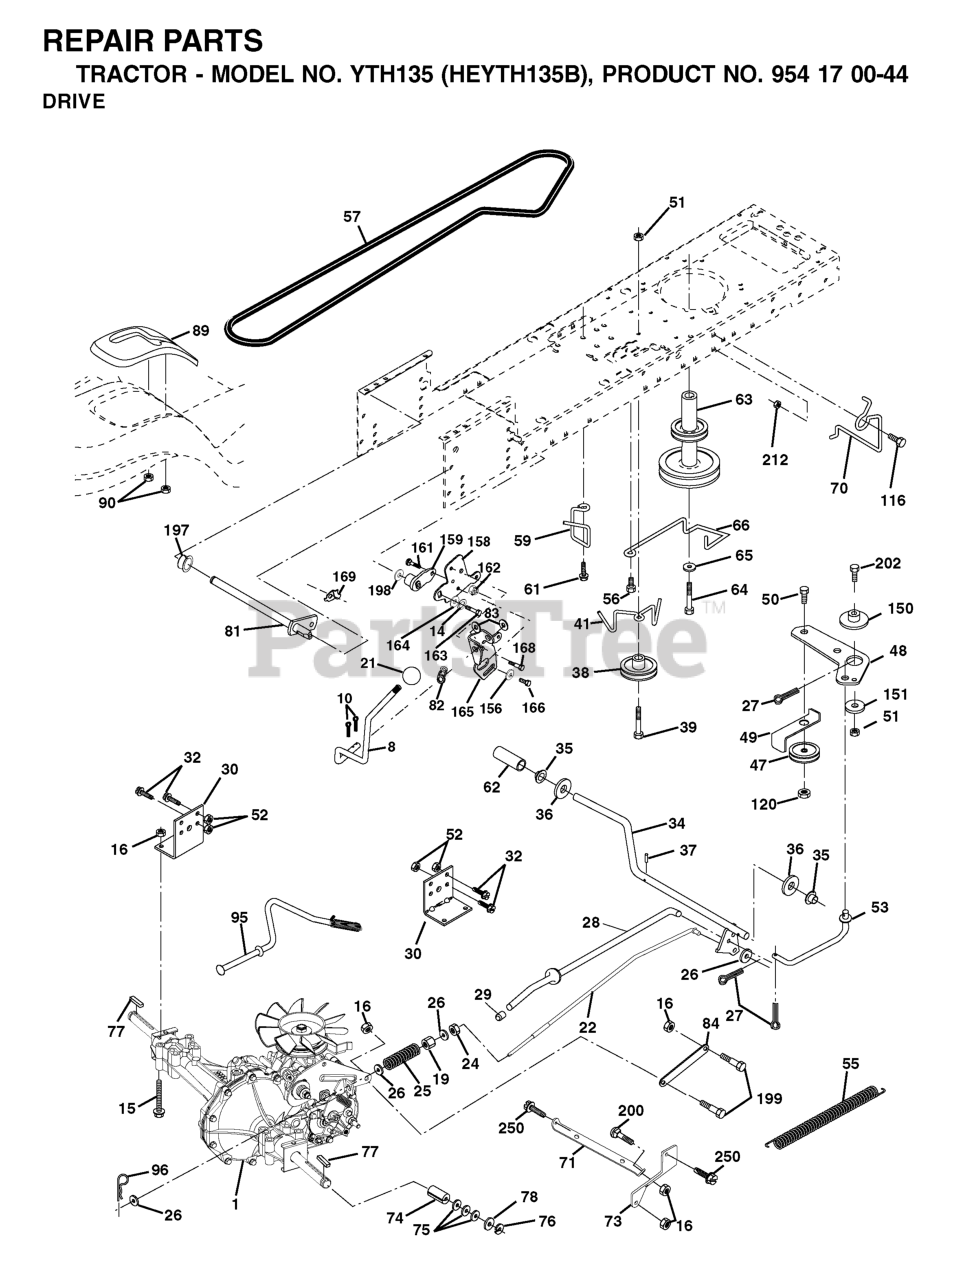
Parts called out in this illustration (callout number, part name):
8	ROD SHIFT FENDER ADJUST STLT
10	PIN COTTER
14	LOCKWASHER
15	BOLT HEX 5/16-18 GR 5
16	NUT.71038.31-18.HEX.NYLOCK
19	NUT
21	KNOB.DUCKHEAD.1/2
22	ROD BRAKE HYDRO
24	NUT
25	SPRING ROD LT
26	WASHER
27	COTTER PIN
28	ROD, PARKING BRAKE
29	PLUNGER CAP
30	BRKT, TRNSXLE MNT 20"
32	BOLT
34	SHAFT, FOOT PEDAL
35	BEARING.NYLON
37	DRIVE PIN
38	PULLEY IDLER COMPOSITE
41	KEEPER, BELT IDLER
47	IDLER PULLEY
48	BELLCRANK, CLUTCH
49	RETAIN BELT
50	BOLT.3/8-16X1.50
52	LOCKNUT
53	LINK, CLUTCH LT
55	SPRING, RETURN LT
56	SCREW.3/8-16
57	DRIVE BELT, LTH & YTH TRACTORS
59	KEEPER, BELT CENTER
61	SCREW 3/8-16X.875
62	COVER, PEDAL (1 2)
63	ENGINE PULLEY
64	BOLT
65	LOCKWASHER
66	KEEPER BELT ENGINE
70	KEEPER BELT ENG
71	STRAP TORQUE LH HYDRO
73	STRAP TORQUE RH HYDRO
74	SPACER AXLE
77	SQUARE KEY
81	SHAFT ASM CROSS TAPERED
82	SHIFT SPRING
83	WASHER
84	LINK TRANSAXLE
89	SHIFT CONSOLE
90	NUT.PUSH.3/16
95	CONTROL ASM. BYPASS HYDRO
96	RETAINER M
116	BOLT D
120	NUT LOCK FLG 3/8-16 UNC
150	SPACER, RETAINER
151	WASHER 12/32X2X10GA
156	WASHER.SRRTD.5/16
158	BRACKET
159	HUB
161	BOLT
162	NUT.CROWNLOCK.1/4
164	Washer 5/8 x .281 x 10 Ga.
165	RP BRACKET
168	BOLT.SHOULDER.5/16-18X
169	PLATE.FASTENING.CROSS.SHAFT
197	NYLINER SNAP 5/8" ID
198	WASHER.NYL.7/8IDX.105"HYD CR
199	BOLT SHOULDER 5/16-18 UNC
212	NUT
250	SCREW 3/8-16X3/4
